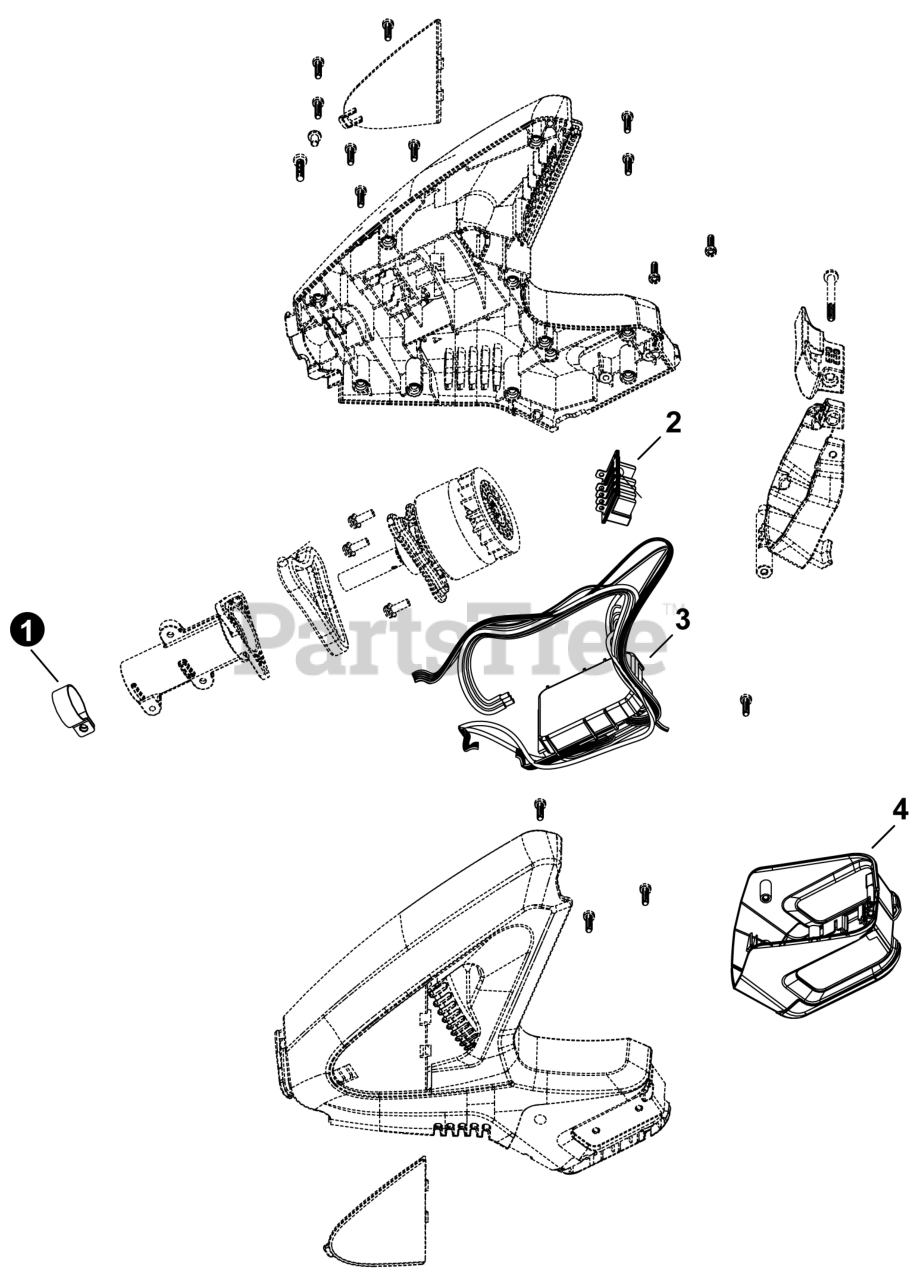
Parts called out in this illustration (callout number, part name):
2	HOLDER, BATTERY
3	PCBA (PRINTED CIRCUIT BOARD ASSEMBLY)
4	BASE KIT
